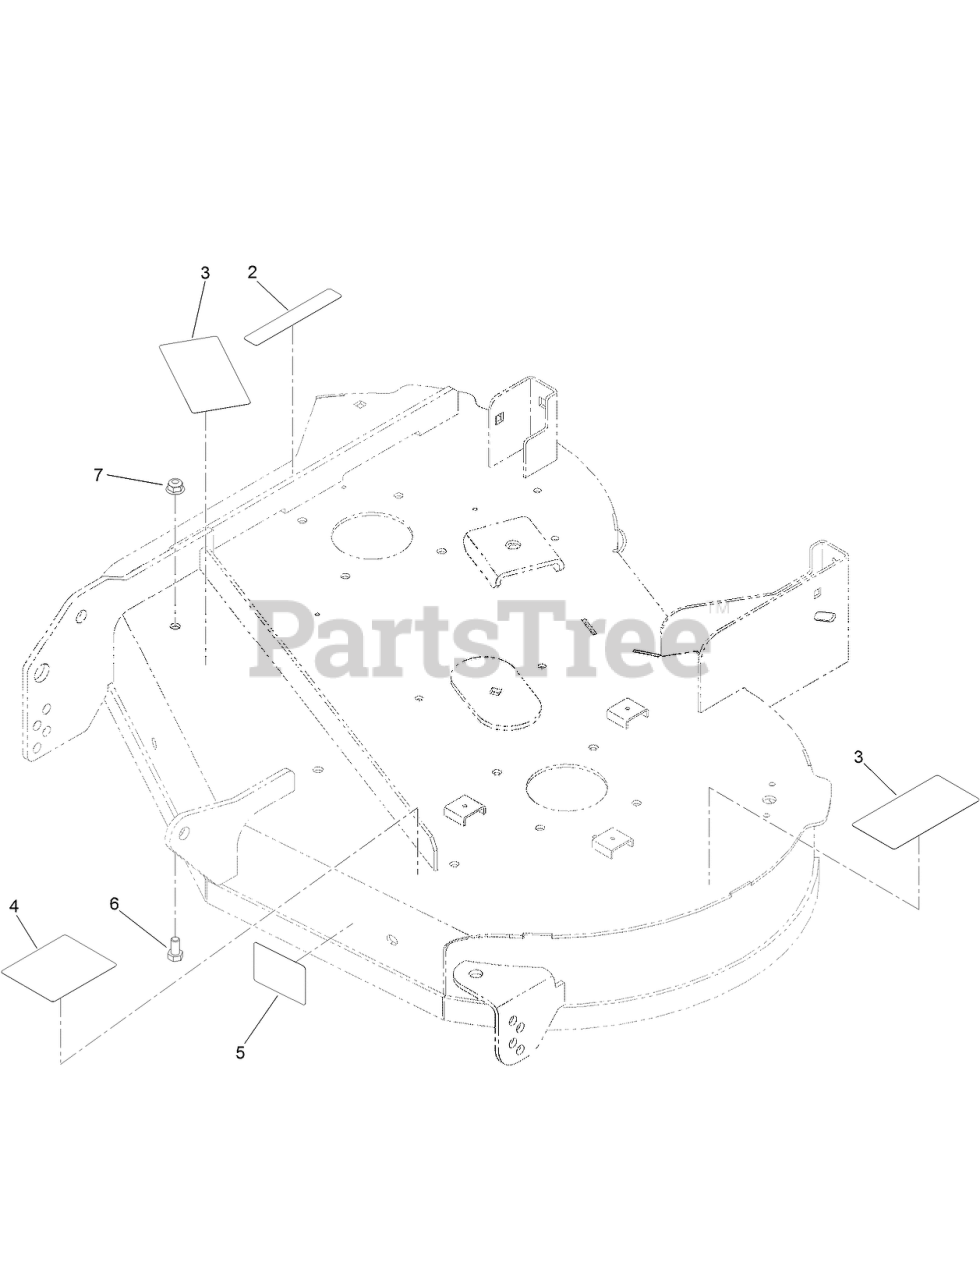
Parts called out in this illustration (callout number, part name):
2	DECAL-DANGER
3	DECAL-DANGER, DECK
4	DECAL-ROUTING, BELT
5	DECAL-SCALP, ANTI
6	SCREW-HH
7	NUT-HF, NI
